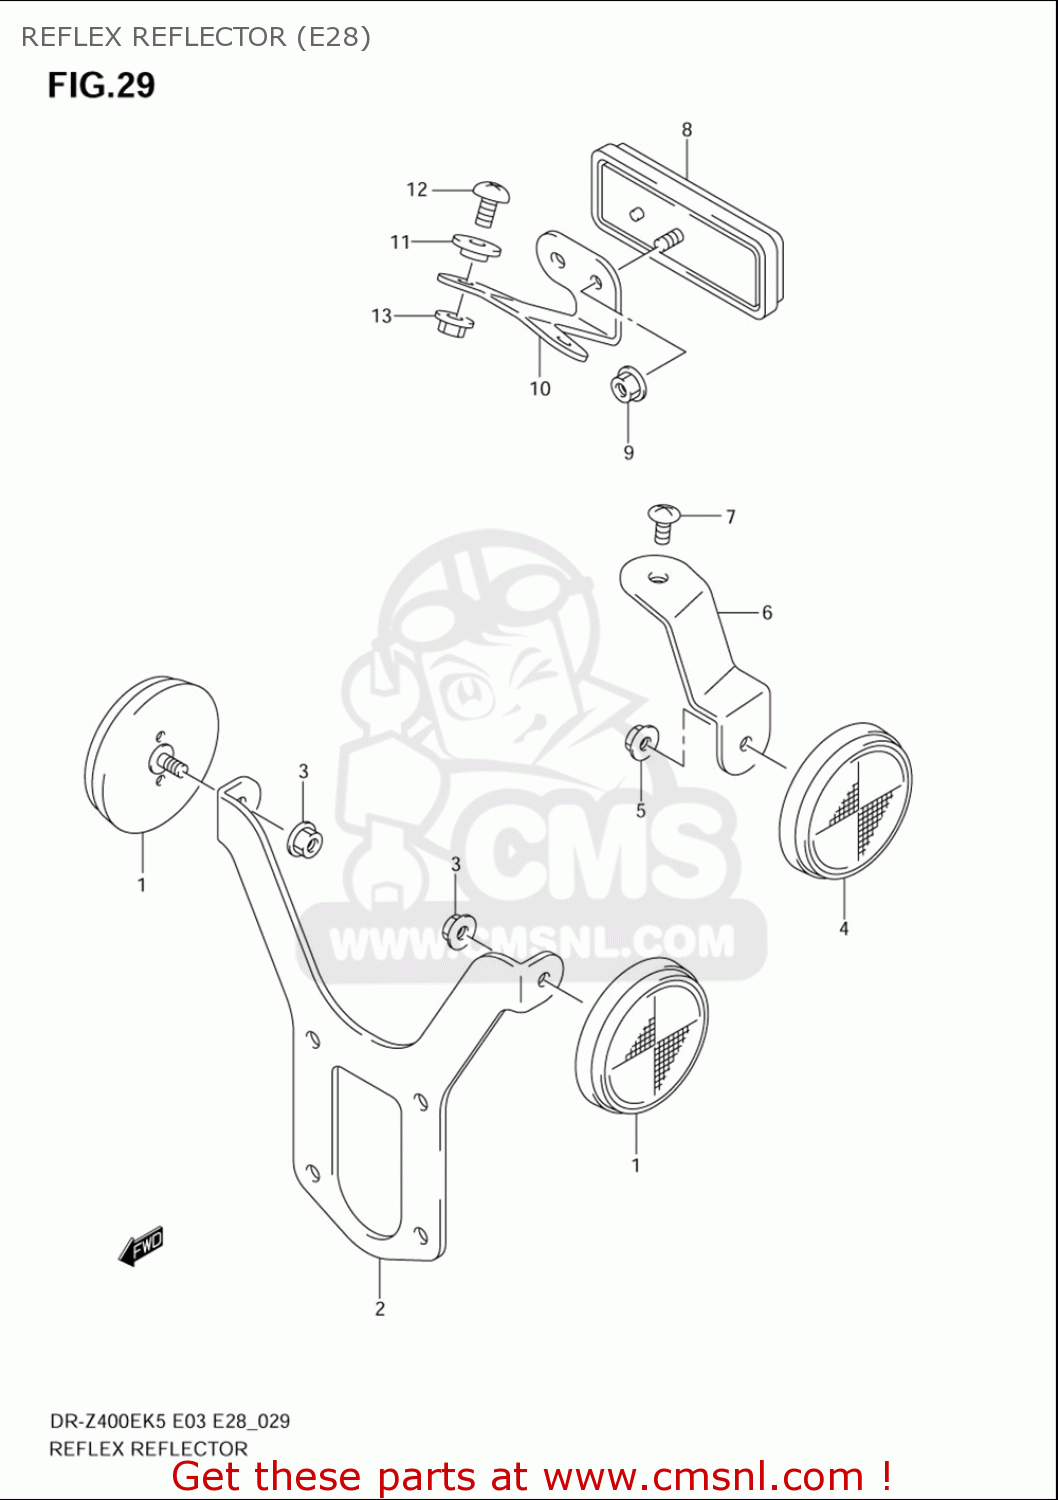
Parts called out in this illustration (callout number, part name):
1	REFLECTOR,REFLEX FR
2	BRACKET,FR SIDE RR
3	NUT
4	REFLECTOR ASSY,RR SIDE
5	NUT
6	BRACKET,RR SIDE RR,R
7	SCREW
8	REFLECTOR ASSEMBLY,REAR
9	NUT
10	BRACKET,RR RR
11	WASHER(5.5X16X1.2)
12	SCREW
13	NUT
